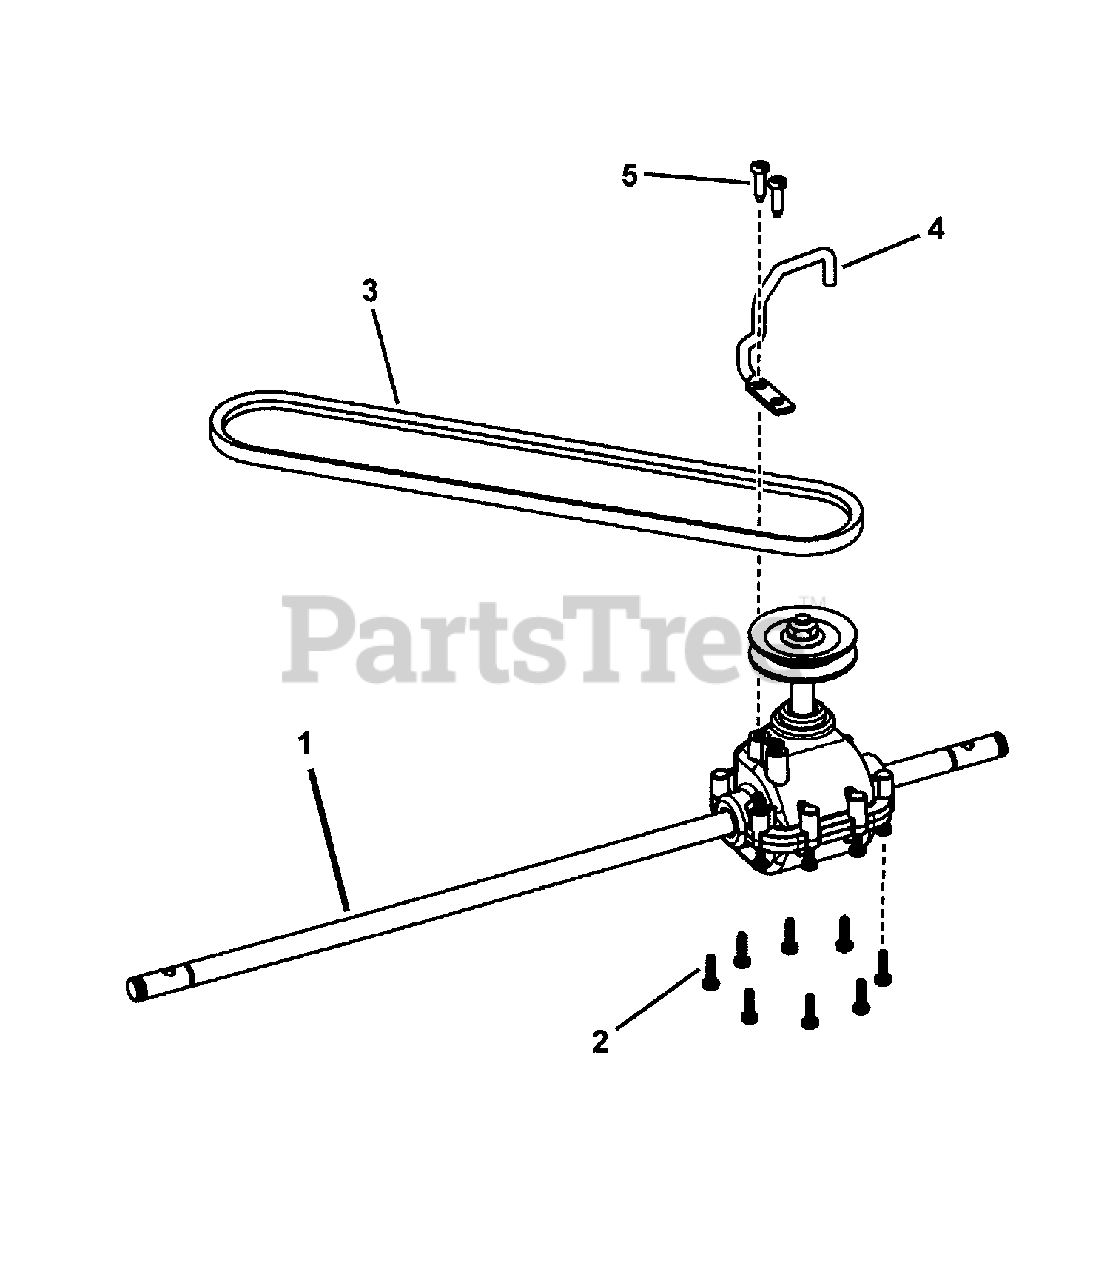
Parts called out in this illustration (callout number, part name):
1	TRANSMISSION, Rocker, 22" WBM HW, VS
2	SCREW, 7mm x 1 x .550 AB Point
3	BELT, Traction Drive, 22" Pivot Handle
4	BELT GUIDE, Transmission, 22" WBM
5	SCREW, #10-16 x 3/4" Pan Head Self-Tap, Combo
